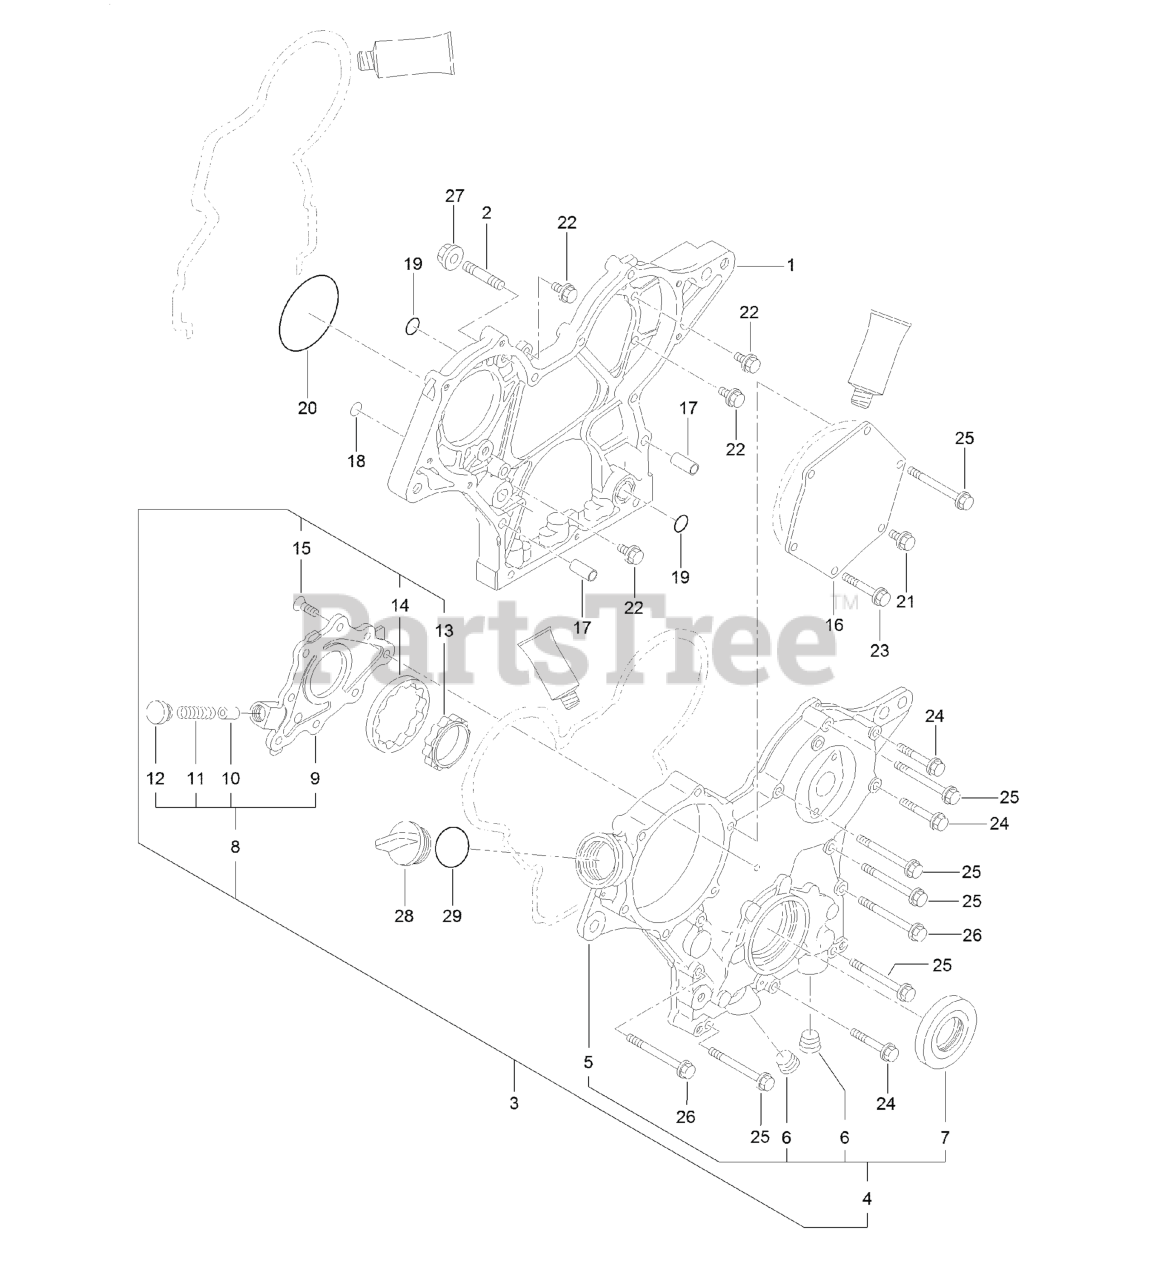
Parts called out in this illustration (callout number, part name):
1	CASE-GEAR
2	BOLT-STUD
3	COVER ASM-GEAR CASE
4	COVER ASSY-GEAR CASE
5	COVER-GEAR CASE
7	SEAL-OIL
8	COVER ASM
9	COVER-PUMP
10	VALVE-RELIEF
13	ROTOR-INNER
14	ROTOR-OUTER
16	COVER-PUMP
17	PIPE-DOWEL
28	COVER-FILLER
